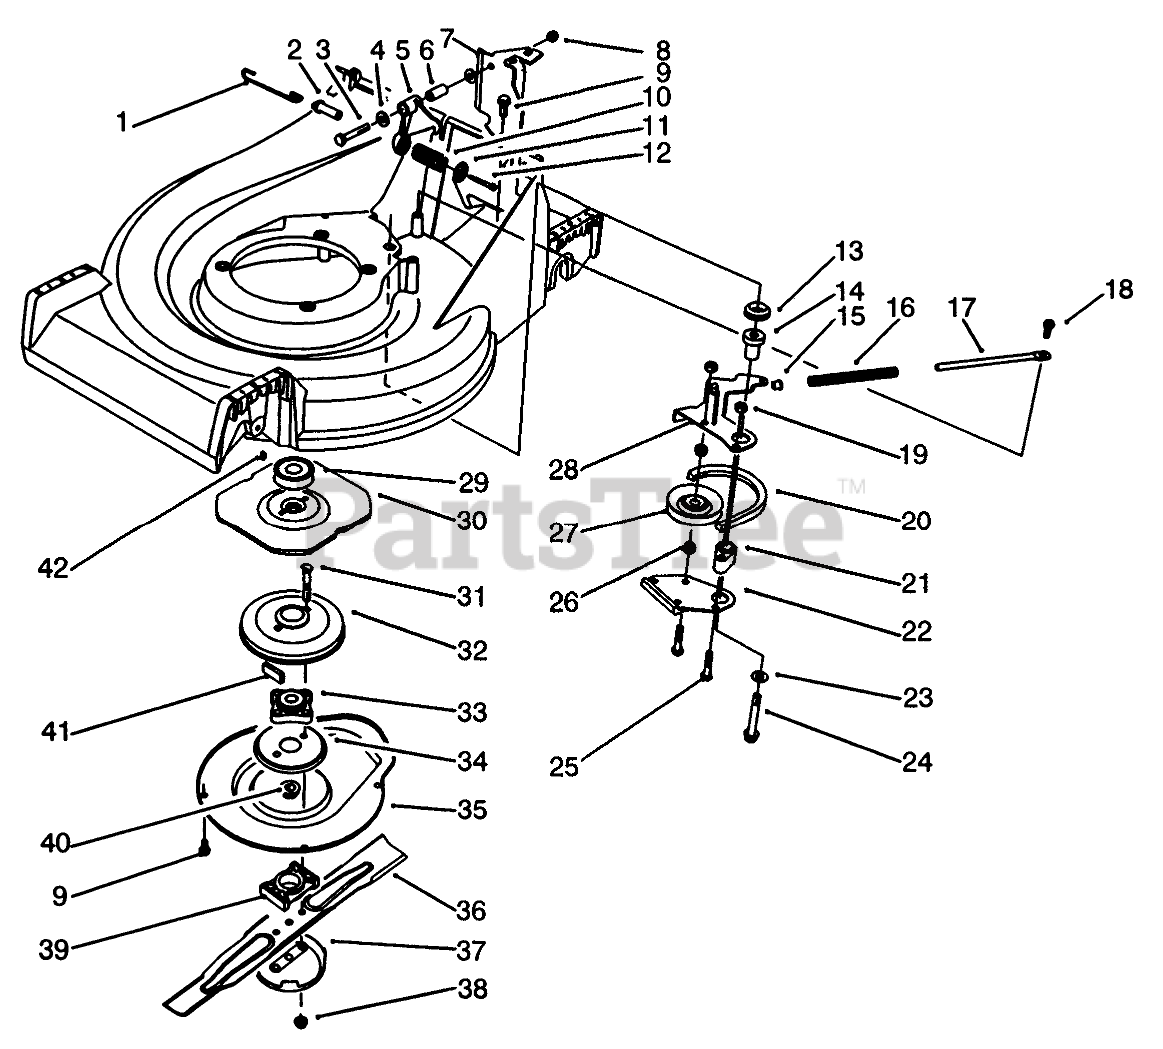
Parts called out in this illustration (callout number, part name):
1	CONTROL LINK
2	SPRING PIN
3	SCREW-HH
4	WASHER-PLAIN
5	CRANK
6	STRAIGHT BUSHING
7	Bracket-Cable Support
9	SCREW-HWHTF
10	COMPRESSION SPRING
11	RETAINER-SPRING
12	SCREW-HWHTF
13	V-RING SEAL
14	BBC PM BUSHING
15	SPACER
16	COMPRESSION SPRING
17	SPRING ROD
18	SCREW-SHOULDER
19	NUT-LOCK, NI
20	V-BELT
21	BRAKE PLATE HUB
22	BRAKE SHOE
23	WASHER-PLAIN
24	3/8-16 X 2-3/4 CAPSCR
25	SCREW-HH
26	IDLER PULLEY HUB
27	PULLEY-IDLER
28	Lever
29	PULLEY
30	FLYWHEEL - BBC
31	BOLT-BLADE
32	BRAKE DRUM
33	HUB ASM
34	Screen-BBC
35	Cover
36	Key
37	CUP-SCALP, ANTI
38	NUT-LOCK
39	SPACER-BLADE
40	NUT-LOCK, NI
41	DAMPENER-VIBRATION
42	KEY-WOODRUFF
